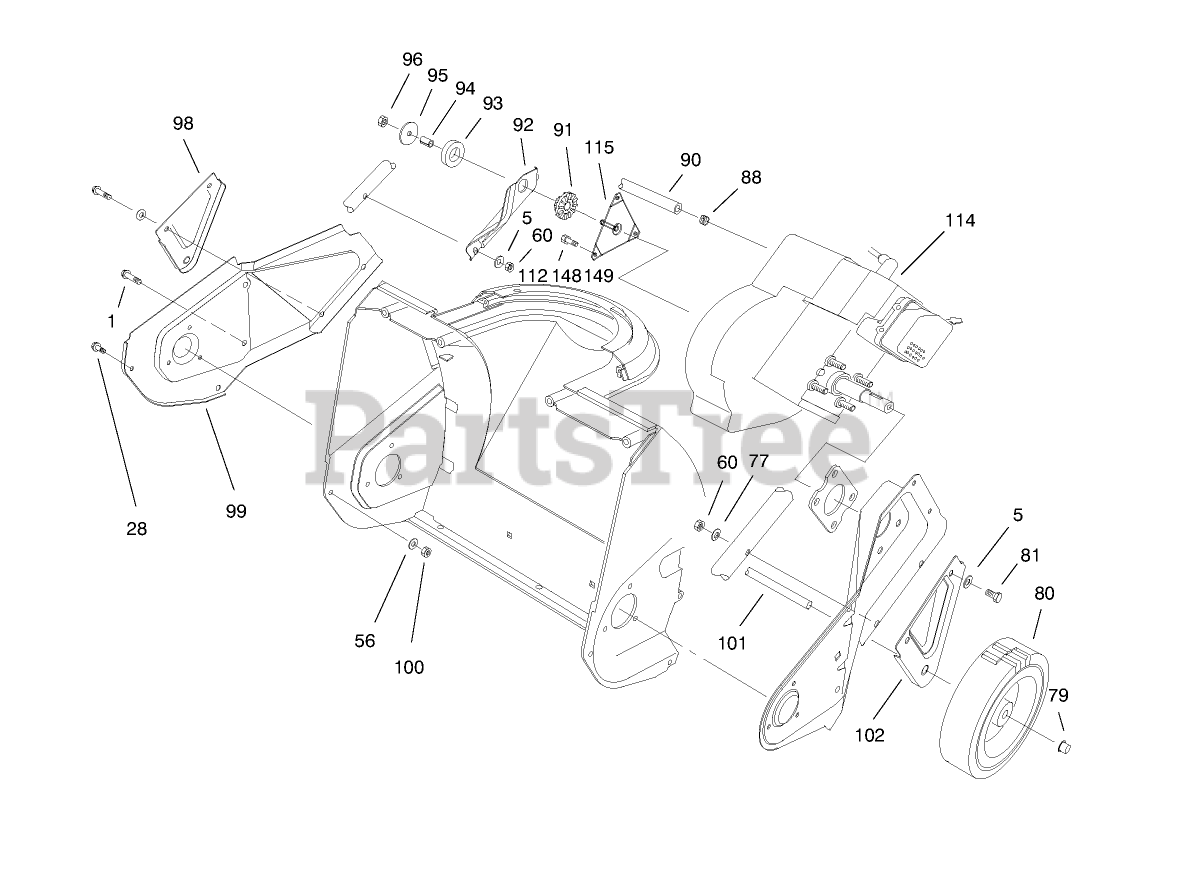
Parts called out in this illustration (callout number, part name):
1	SCREW-PLASTIC
5	WASHER-FLAT
56	WASHER-FLAT
60	NUT-LOCK, NI
77	WASHER
79	RETAINER-PUSH ON
80	WHEEL
81	SCREW-HH
88	CLAMP-HOSE
90	LINE-GAS
91	BUSHING-ISOLATOR
92	Support-Engine
93	RING-ISOLATOR
94	SPACER-TUBULAR
95	WASHER-FLAT
96	NUT-LOCK, NI
98	Bracket-Wheel
99	Sideplate-RH
100	NUT-LOCK, NI
102	Bracket-Wheel
112	SCREW
115	BRACKET AND STUD ASM
148	SCREW
149	WASHER-LOCK / EXT
